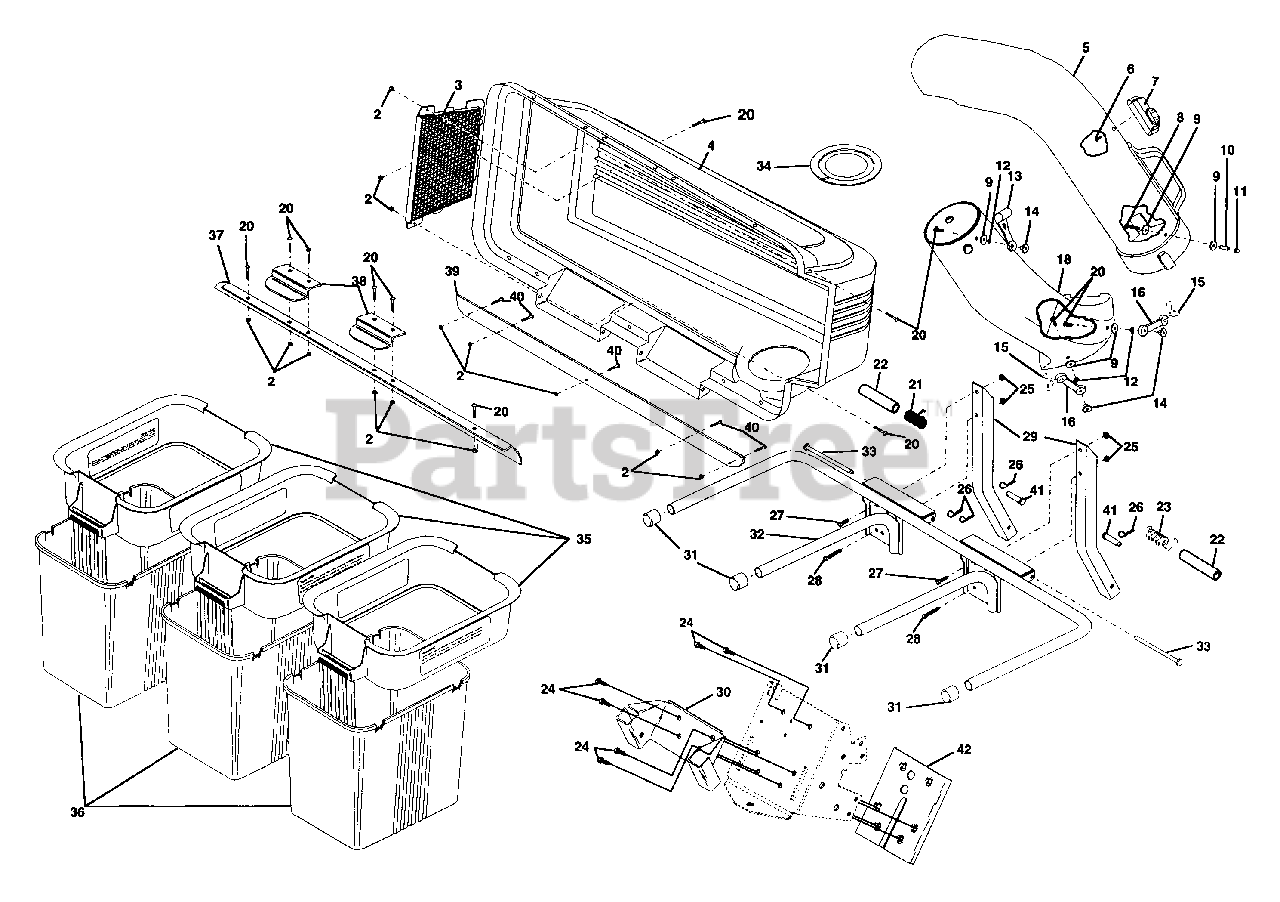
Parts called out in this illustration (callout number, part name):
2	Nut, Crownlock #10-24
3	Screen, Cover
4	Cover
5	Chute, Upper
6	Screw, Special #10-14 x 1/2
7	Dump Bagger Indicator
8	Screw, #10-24 x 1-1/8
9	Washer 3/16 x 3/4 x 16 Ga.
10	Spacer, Split
11	Nut, Acorn #10-24
12	Washer, Lock
13	Latch, Chute
14	Nut, Weld
15	Latch, Hook
16	Rubber, Latch
18	Chute, Lower
20	Screw #10-24 x 5/8
21	Spring, Cover L.H. (black)
22	Spacer, Cover
23	Spring, Cover R.H. (gray)
24	Bolt, 7/16-14 x 3/4
25	Locknut 5/16 x 18
26	Spring, Retainer
27	Bolt, Hex 5/16-18 x 3/4
28	Bolt, Hex 5/16-18 x 2-1/4
29	Bagger, Support Post
30	Bracket, Mounting
31	Plug, Tubing End
32	Bagger, Frame
33	Pin, Hinge
34	Gasket, Cover
35	Container, Top
36	Container, Bottom
37	Seal, Cover
38	Latch Handle, Cover
39	Strip, Seal
40	Screw #10-24 x 1/2
41	Pin, Clevis
42	Plate, Reinforcement
